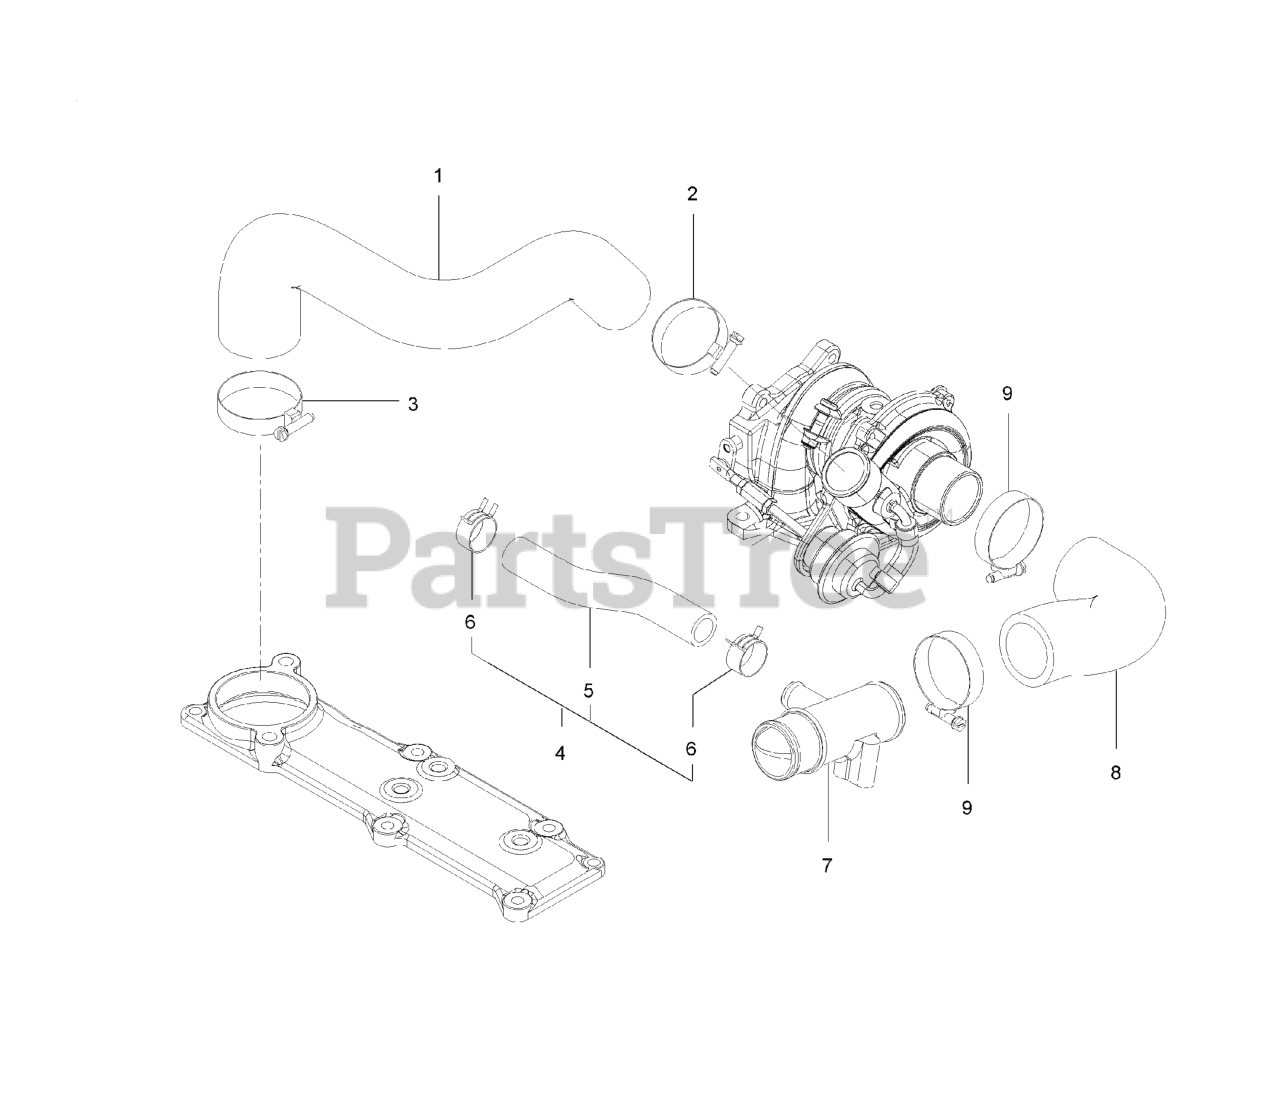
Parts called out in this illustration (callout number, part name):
1	HOSE-AIR INTAKE
2	CLAMP-HOSE
3	CLAMP-HOSE
4	HOSE ASM-BREATHER
5	Hose-Breather
6	CLIP-HOSE
7	JOINT-BREATHER
8	HOSE-AIR INTAKE
9	CLAMP-HOSE
